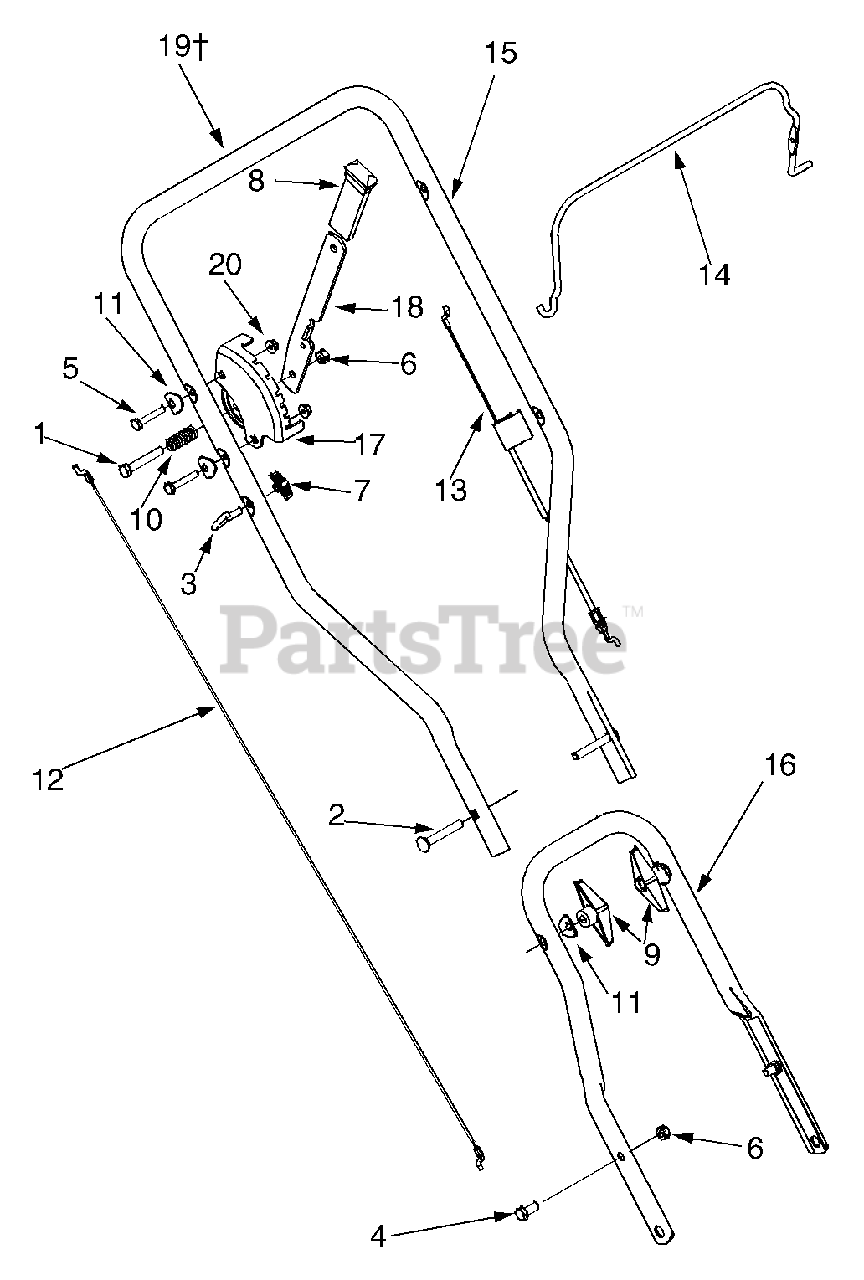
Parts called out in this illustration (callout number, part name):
1	Screw, 5/16-18
2	Screw, 5/16-18
4	Screw, 5/16-18
6	Hex Lock Nut, 5/16-18
9	Wing Knob
10	Compression Spring
11	Saddle Washer,.320 ID x.93 OD
12	Wheel Adjustment Cable
13	Control Cable (Tecumseh)
19	Foam Grip
20	Hex Flange Nut, 1/4-20
